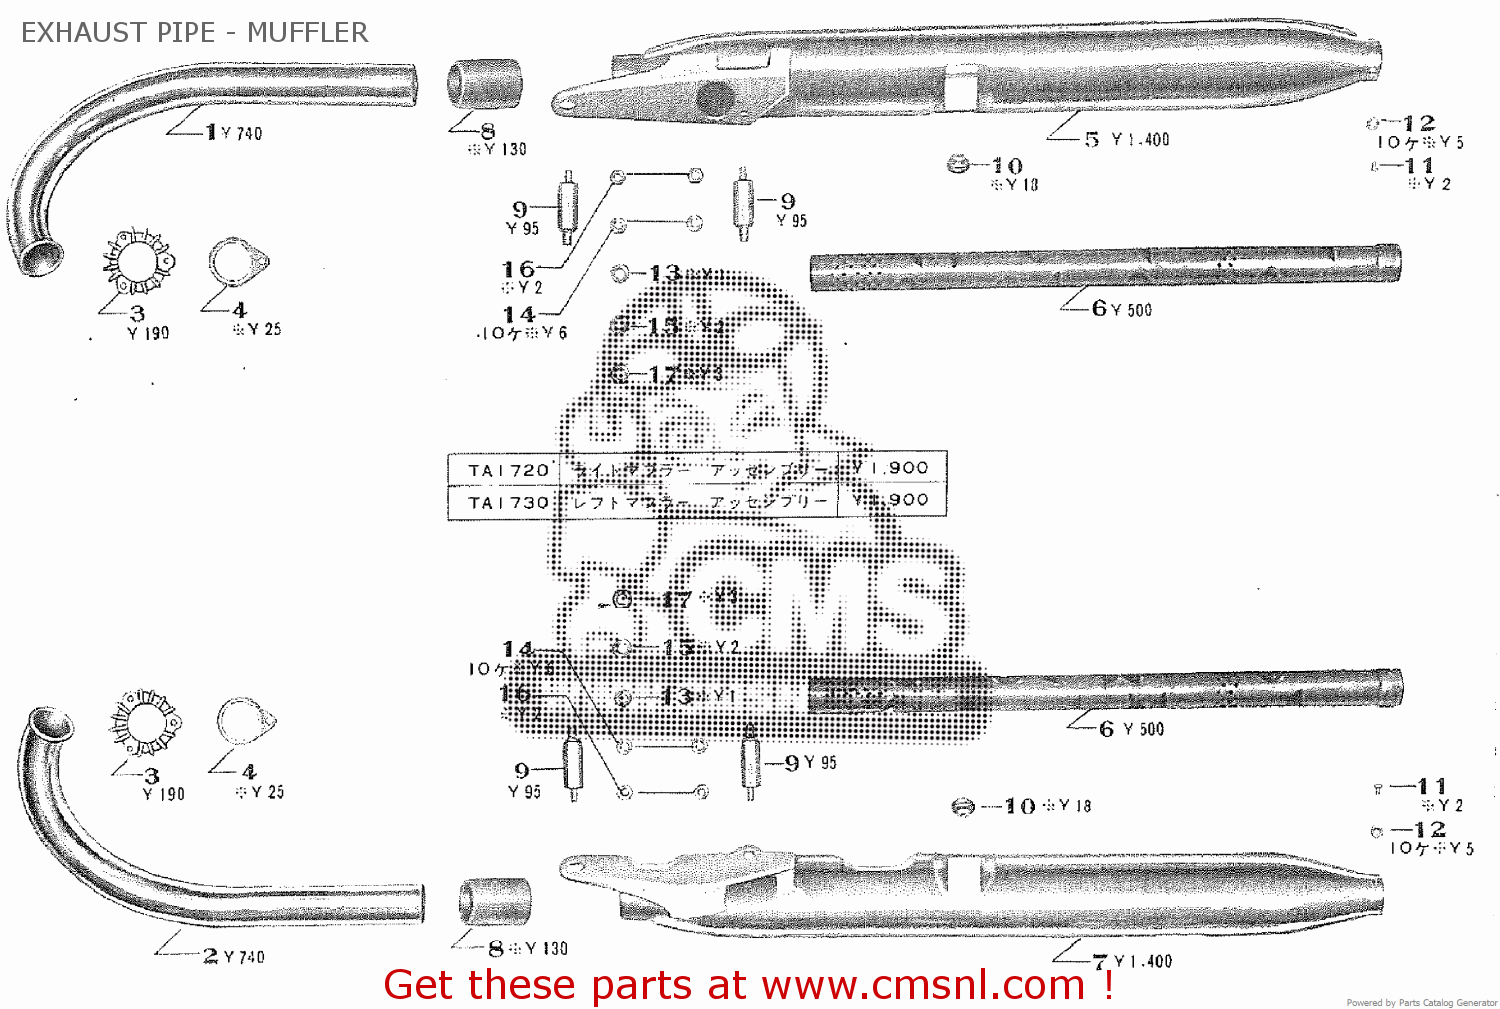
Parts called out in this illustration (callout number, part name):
1	RIGHT EXHAUST PIPE
2	LEFT EXHAUST PIPE
3	EXHAUST PIPE JOINT CLAMP
4	EXHAUST PIPE GASKET
5	RIGHT MUFFLER ASSY.
6	BAFFLE PIPE COMP.
7	LEFT MUFFLER BODY COMP.
8	MUFFLER JOINT RUBBER
9	MUFFLER STAY BOLT
10	MAIN STAND STOPPER
11	5X8 CROSS SCREW
12	5MM LIGHT PLANE WASHER
13	8MM PLANE WASHER
14	8MM SPRING WASHER
15	10MM SPRING WASHER
16	8MM HEXAGON NUT
17	10MM HEXAGON NUT
